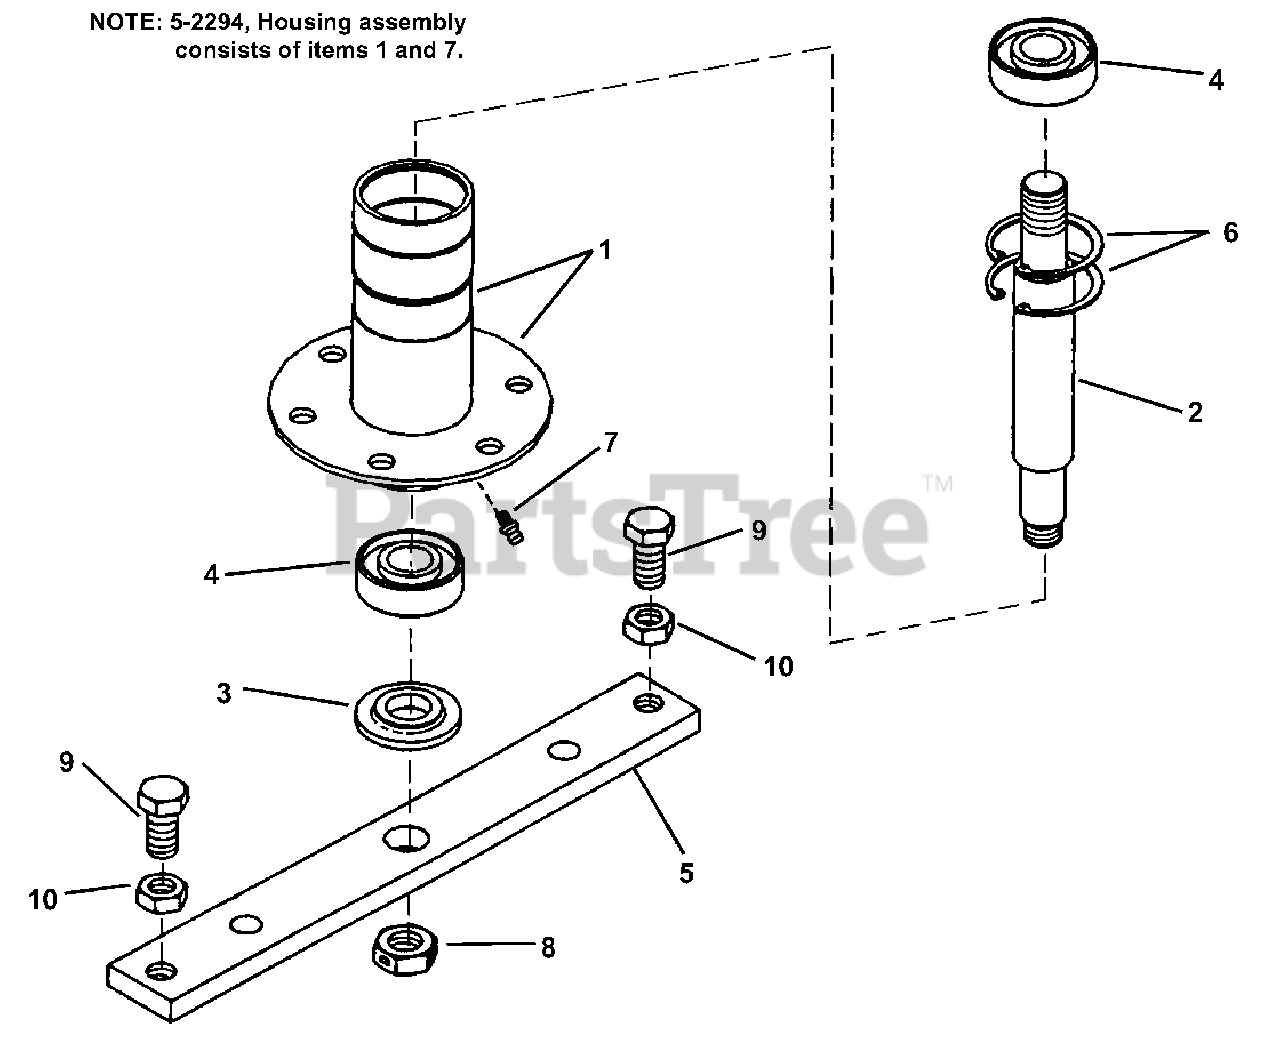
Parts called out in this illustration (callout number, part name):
1	HOUSING, Spindle (weldment) (5.575" overall length)
2	SPINDLE, Shaft (7.54" overall length)
3	WASHER
4	BEARING, Spindle
5	HOLDER, Blade
6	RING, 1-3/4" External Retaining
7	FITTING, Lube (Press fit for .187 hole-no ball)
8	NUT, 5/8-18 Hex Center Lock Jam
9	SCREW, 1/2-20 x 1-1/4" Hex Head Cap
10	NUT, 1/2-20 Hex Jam
52294	HOUSING ASSEMBLY
